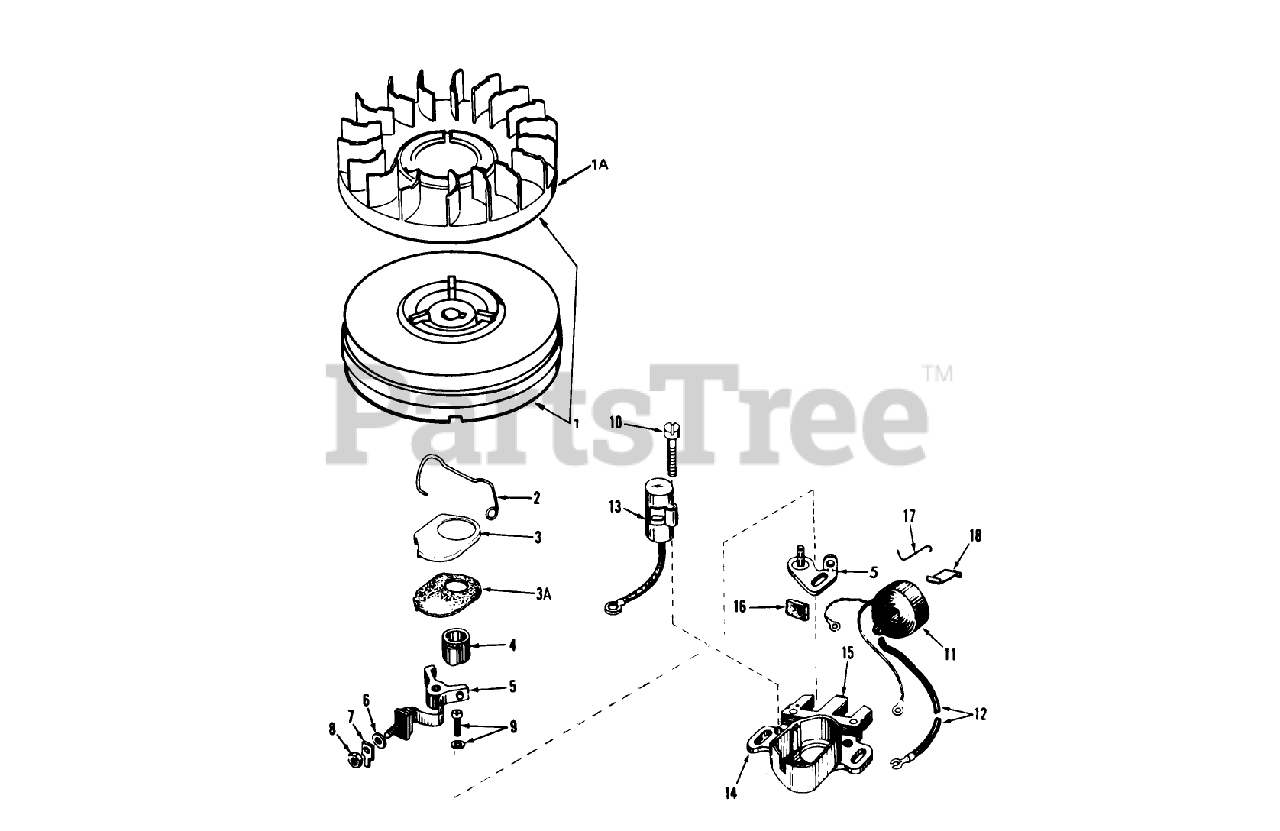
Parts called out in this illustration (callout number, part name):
1	Flywheel (Incl. Ref. #1A)
1A	Fan
2	Spring Breaker Box
3	Cover-Dust
3A	Gasket-Dust Cover
4	Cam-Breaker
5	Breaker Assy.
6	Washer
7	Terminal, Ground
8	DECAL
9	Breaker Screw
10	Condenser Screw
11	Coil Assy. (Incl. No. 12)
12	Wire, Lead
13	Condenser
14	Core Plate
15	Stator Assy. (Incl. Ref. #2 thru 11, 13, 14, 16, 17 19)
16	Felt,Cam Wiper
17	Clip, Coil
18	Spring Coil Wedge
